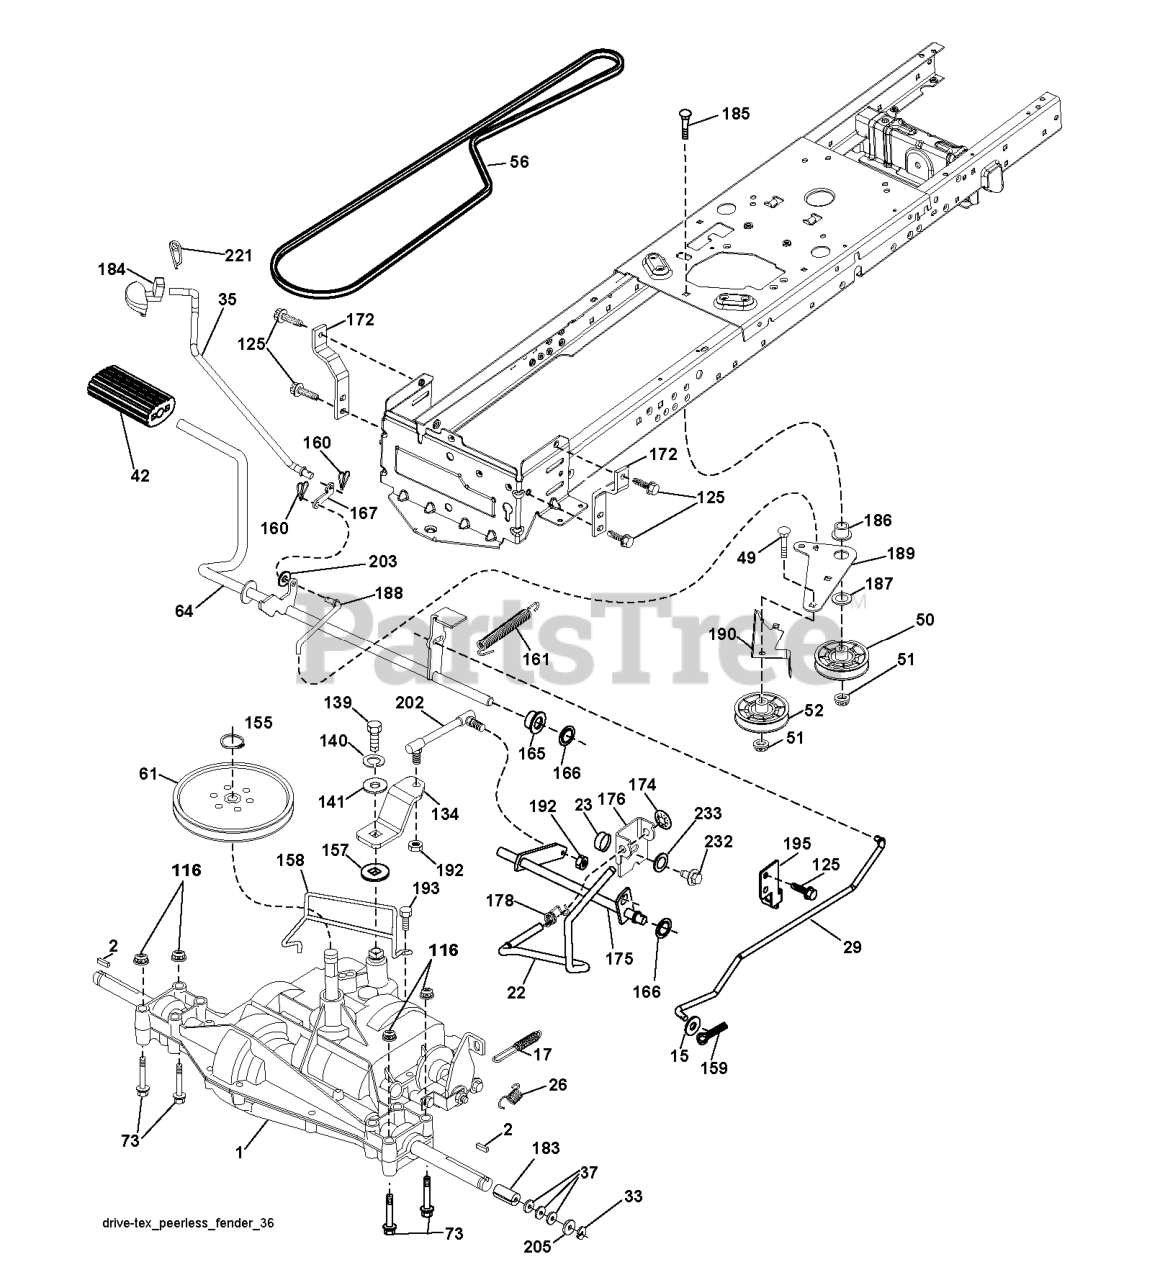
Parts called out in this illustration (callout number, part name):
2	SQUARE KEY
15	WASHER
17	SPRING.BRAKE.PEERLESS.TEX
22	ROD.SHIFT.FENDER.TLT.2006
23	KNOB.DUCKHEAD.1/2
26	SPRING.BRAKE.RTN.GR.DR
29	ROD.BRAKE.PEERLESS
35	ROD.CNTRL.PARK.PREDATOR.LT.TEX
42	PEDAL COVER T
50	IDLER.FLAT.910.OFFSET
51	NUT LOCK FLG 3/8-16 UNC
52	IDLER.V-GROOVE.910.OFFSET
56	V-BELT.TRACTOR.DRIVE.P
61	PULLEY TRANS
64	SHAFT.ASM.PEDAL.BRAKE.
73	BOLT HEX 5/16-18 GR 5
116	NUT LOCK HEX FLANGE 5/16-18
125	SCREW
139	BOLT 1/4-28X3/4
140	LOCKWASHER
155	RETAINING RING LT
157	WASH-SHFT PLT LT
158	KEEPER.PMS.18/20.D4365
159	COTTER PIN
160	RETAINER CLIP
161	SPRING, RETURN LT
165	BUSHING.SHAFT.BRAKE.HAND
166	NUT.PUSH.625
167	LATCH.BRAKE.SPRING
172	STRAP.TRQ.LH.GEAR.DRIV
174	NUT.PUSH.500.2006
175	SHAFT ASM SHIFT
176	ARM.CLEVIS.ROD.SHIFT
178	SPRING.SHIFT.GT2006
183	SPACER AXLE
184	HANDLE PARKING BRAKE
186	SPACER.RETAINER
187	WASHER 12/32X2X10GA
188	RP.LINK.CLUTCH.GROUND.DRIVE
189	BELLCRANK.GROUND.DRIVE.TEX.
190	KEEPER.BELLCRANK.DRIVE
192	NUT LOCK CENTER 1/4 -28 FNTHD
193	SCREW 5/16"
195	BRKT.ROD.BRAKE.PEERLES
202	LINK.SHIFT.PMST.18" (SPG1286)
203	WASHER
221	RETAINER.SPRING.CLIP.H
232	BOLT FIN HEX 7/16-14 X 1
233	WASHER SERRATED
